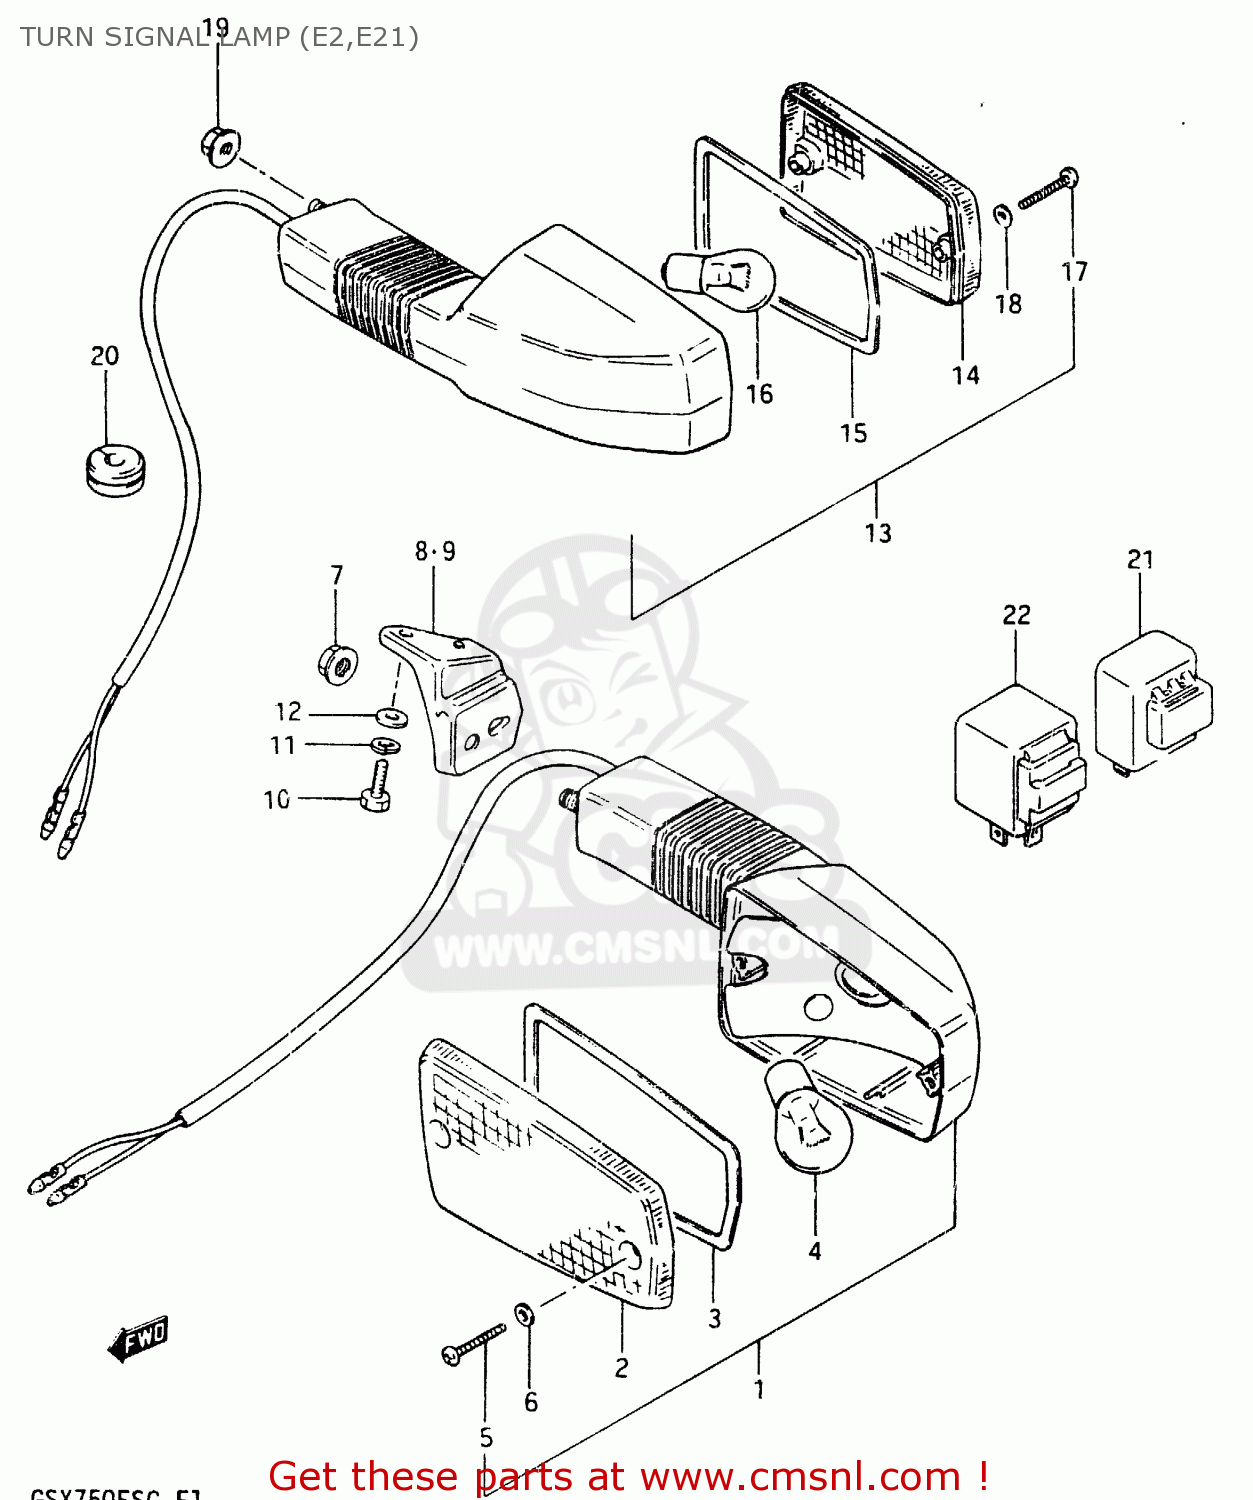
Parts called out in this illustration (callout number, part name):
1	LAMP ASSY,FR TURN SIGNAL
2	LENS
3	GASKET (NAS)
4	BULB(12V21W)
5	SCREW
6	GASKET (NAS)
7	NUT
8	BRACKET,FRONT TURN SIGNAL
9	BRACKET,FRONT TURN SIGNAL
10	BOLT
11	WASHER,LOCK,8.
12	WASHER
13	LAMP ASSY, REAR TURN SIGNAL
14	LENS
15	GASKET (NAS)
16	BULB(12V21W)
17	SCREW
18	GASKET (NAS)
19	NUT
20	GROMMET
21	RELAY ASSEMBLY,TURN SIGNAL
22	RELAY ASSY,TUR
